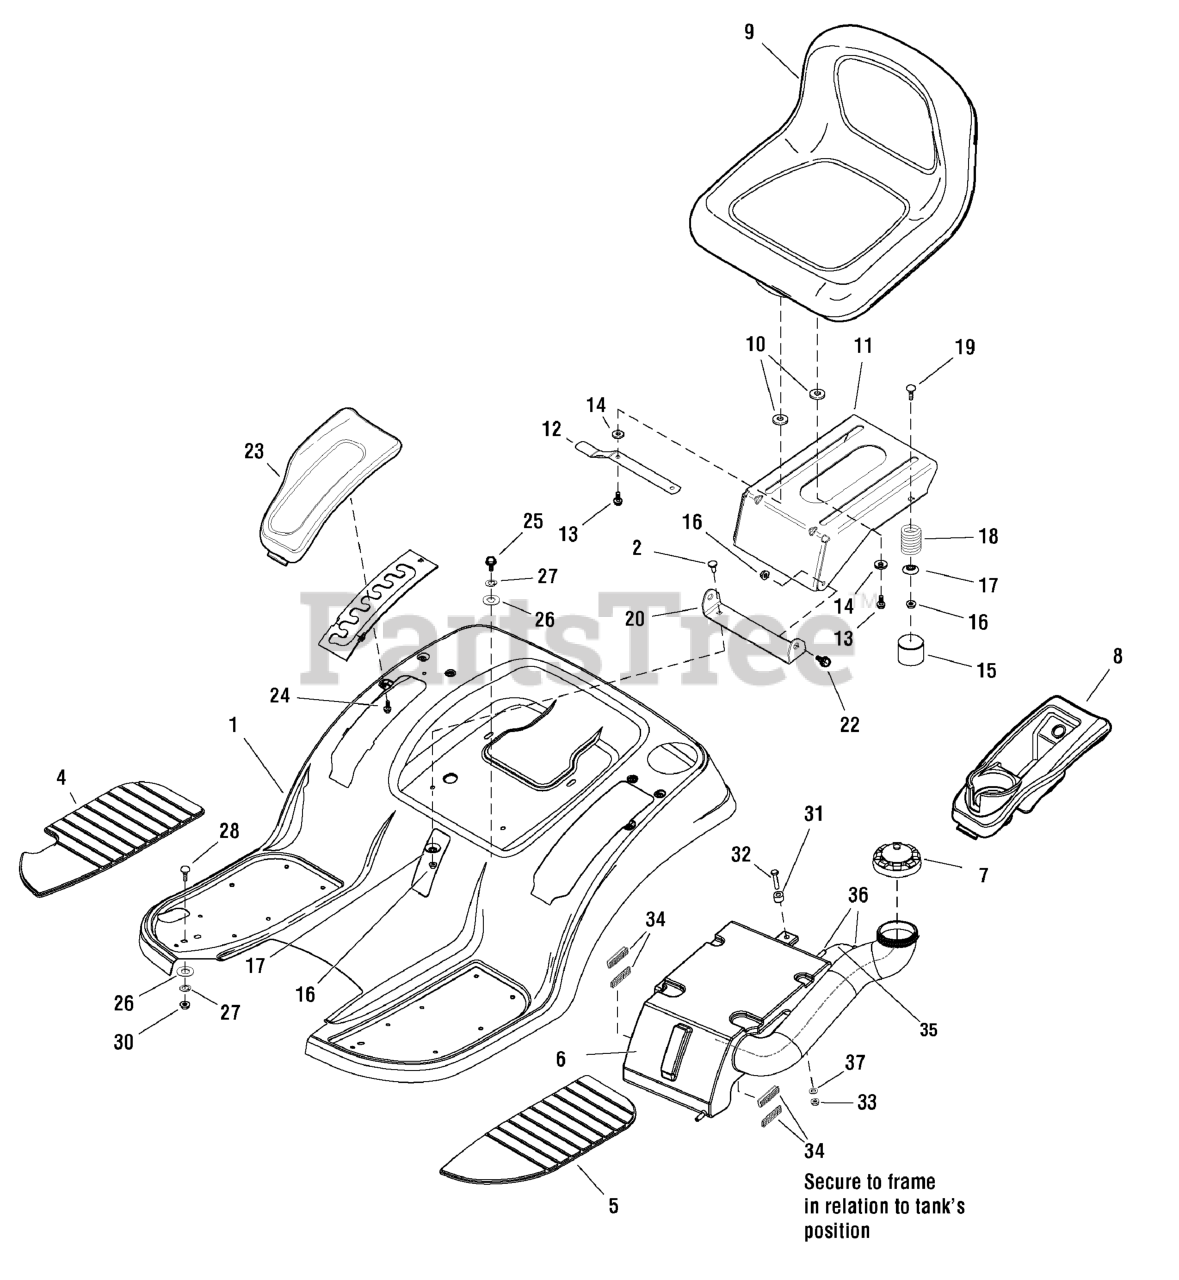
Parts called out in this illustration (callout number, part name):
1	SEAT DECK, Black
2	BOLT-Round Head Shoulder, 5/16-18 x 3/4
4	PAD, Footrest, R.H.
5	PAD, Footrest, L.H.
6	TANK, Fuel
7	CAP, Fuel Tank
8	POD, L.H.
10	SPACER, 5/16 ID x 1-1/4 OD x 5/16
11	SUPPORT, Seat
12	LATCH, Seat
13	CAPSCREW,Hex Flange Whiz Lock, Dog Point, 5/16-18 x 1
14	WASHER, 5/16
15	COVER, Spring
16	NUT, Hex Flange, ESNA, 5/16-18
17	WASHER, Spring, 5/16 x 1 1/4
18	SPRING, Compression
19	BOLT, Carriage, 5/16-18 x 3/4
20	PIVOT, Seat
22	BOLT, Shoulder, 5/16-18 x 15/32
23	POD, R.H.
24	CAPSCREW, Hex Washer Head, Plastite, 1/4 x 1/2
25	BOLT, M8 x 16
26	WASHER, 8.4
27	WASHER, 8
28	BOLT, M8 x 20
31	DISTANCE, Lift
32	BOLT, M6 x 30
34	BRAID, Steel Insert
35	HOSE, Air Escape
37	WASHER, 6.6
